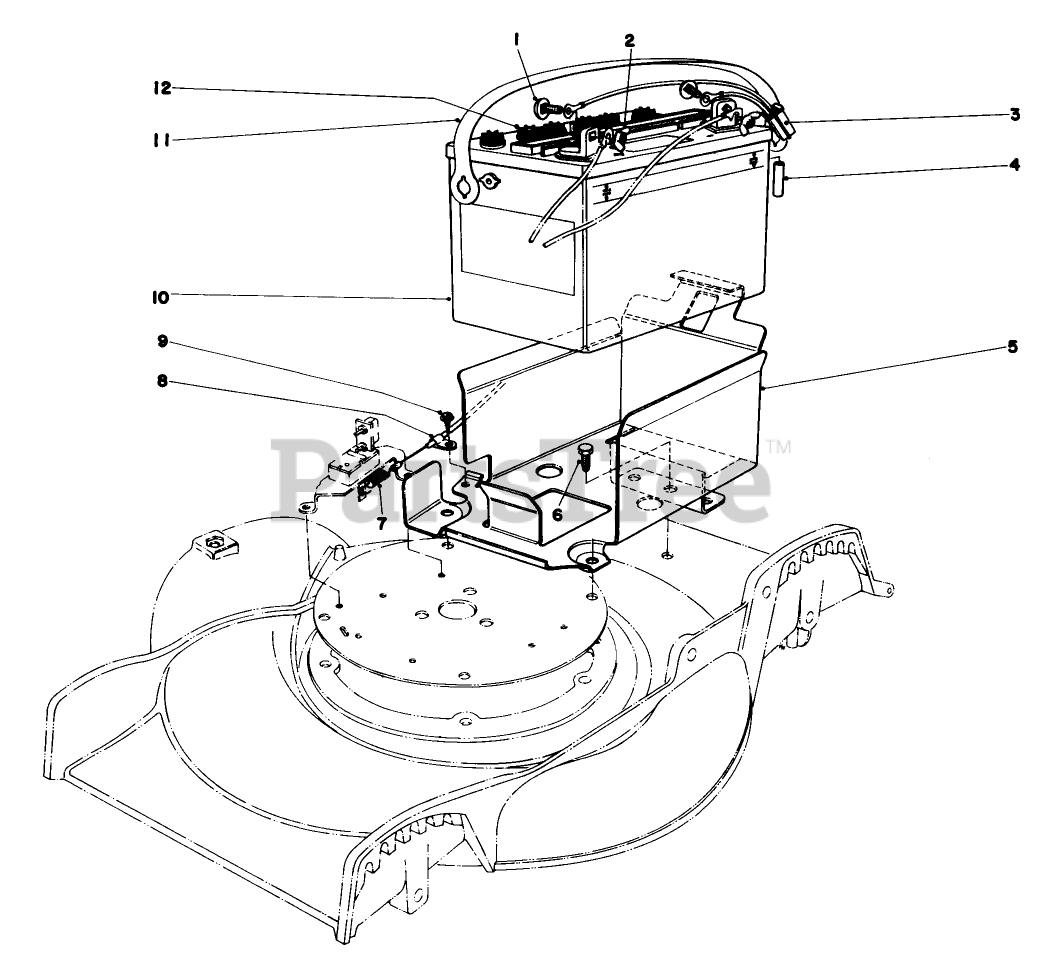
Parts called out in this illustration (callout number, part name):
2	NUT-WING
6	SCREW-THD ROLL, HWH
9	SCREW-HWHTF
